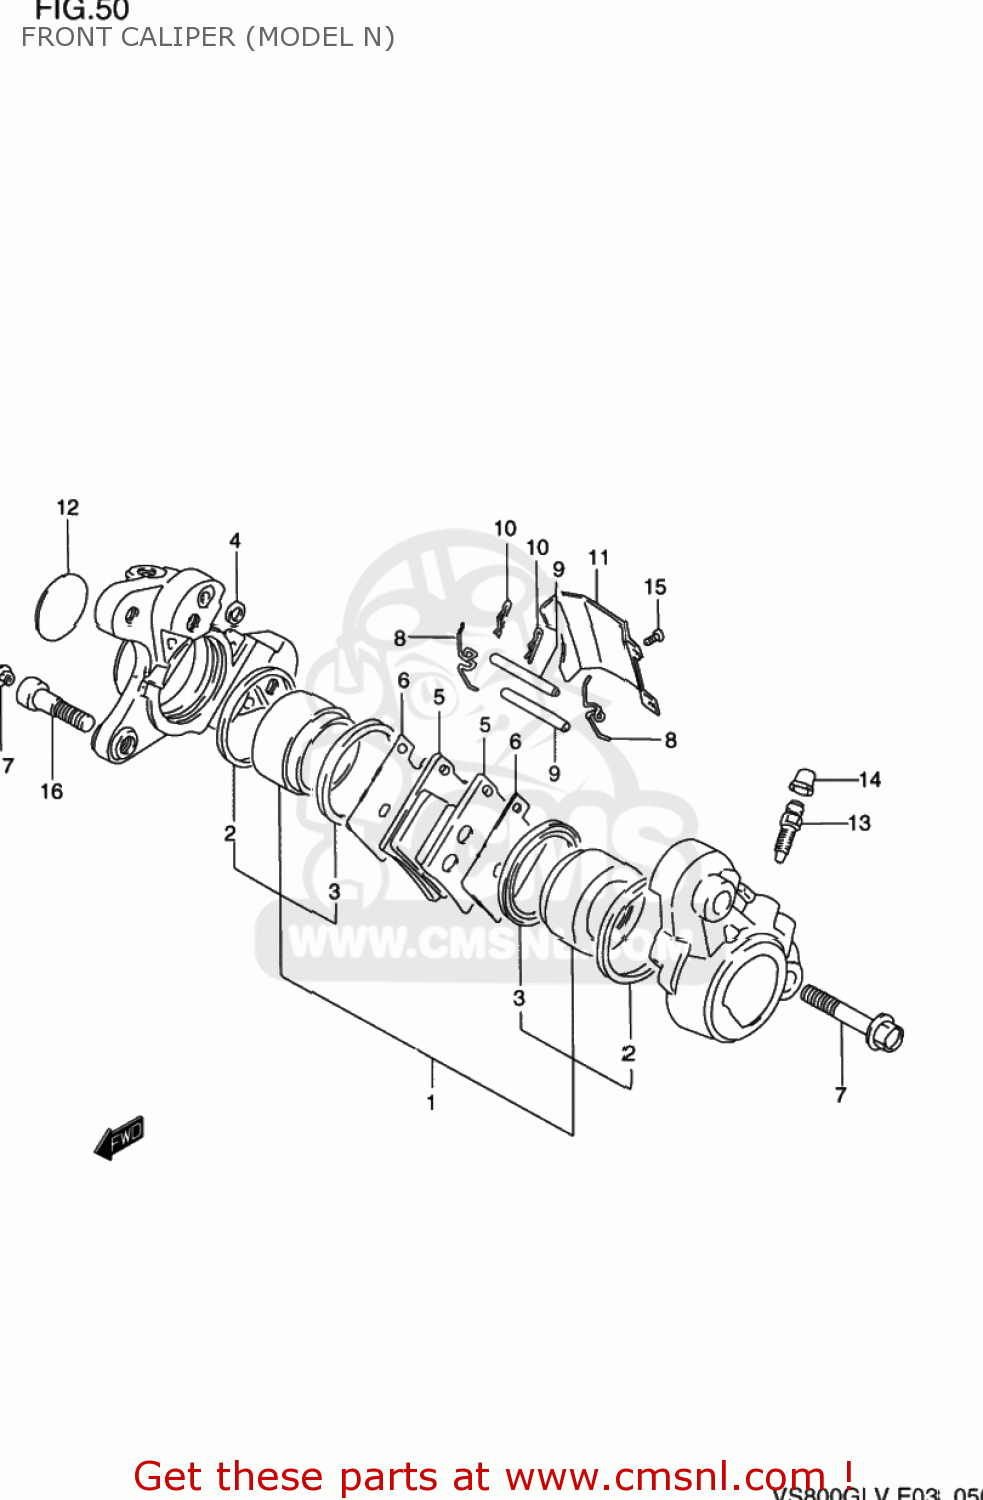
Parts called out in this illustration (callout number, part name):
1	PISTON SET
2	SEAL,FR CALIPE
3	BOOT,PISTON
4	SEAL,JOINT
5	PAD
6	SHIM,PAD
7	BOLT,HOUSING
8	SPRING
9	PIN,PAD
10	CLIP,PAD PIN
11	COVER,CALIPER
12	CAP,CALIPER
13	BLEEDER
14	CAP,BLEEDER PLUG
15	SCREW,CALIPER COVER (4X
16	BOLT(10X33)
17	CAP(OD:12)
